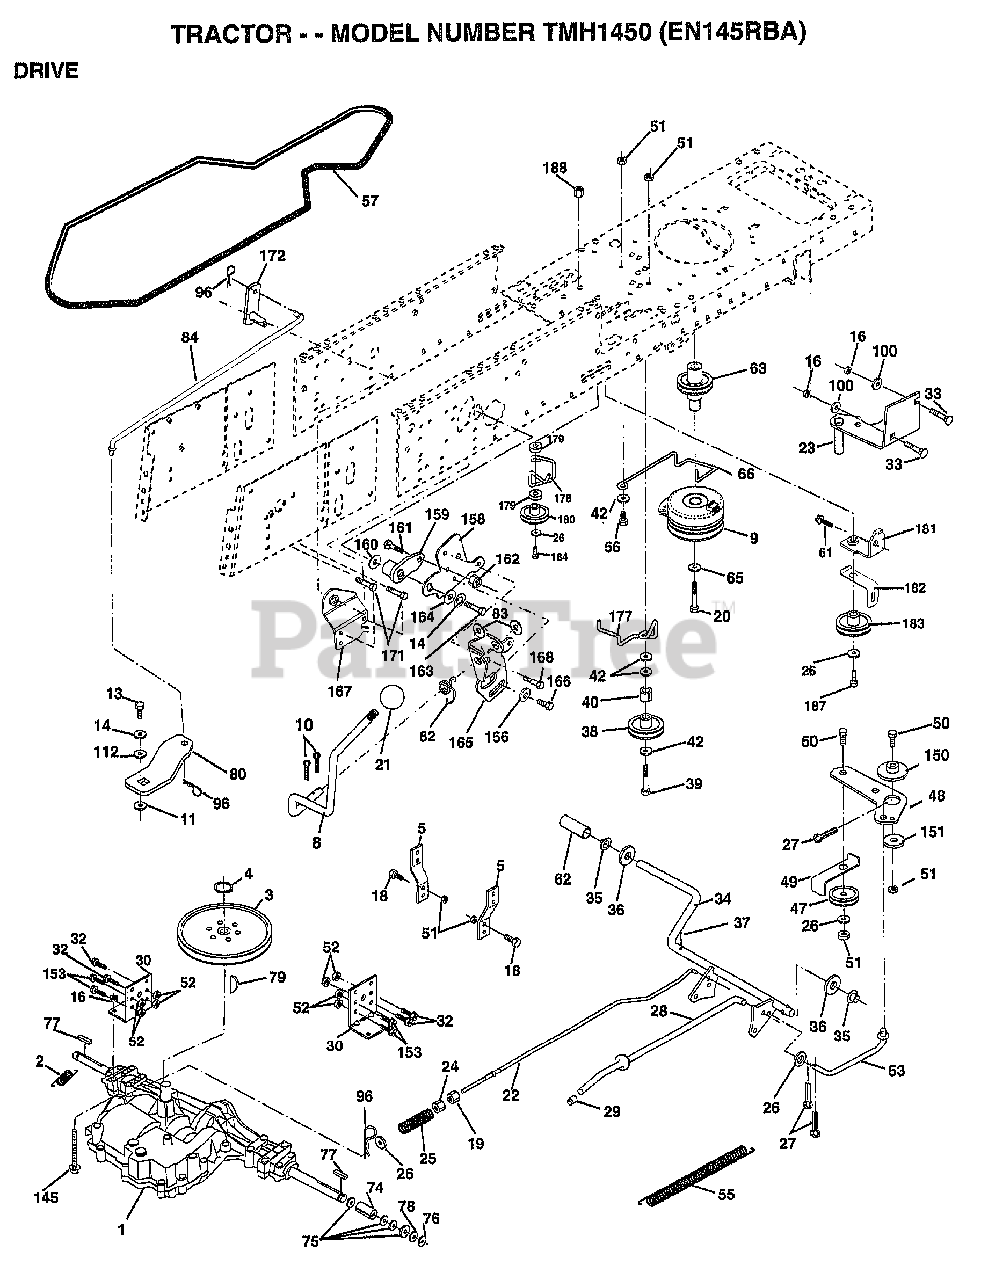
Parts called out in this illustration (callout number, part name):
2	SPRING.BRAKE.RETU
3	"PULLEY.TRANSAXLE.7"""
5	STRAP TORQUE
8	ROD.SHIFT.FENDER.ADJ.LT.CRD
9	CLUTCH.ELEC.EVX
10	PIN COTTER 1/8
11	WASH-SHFT PLT LT
13	BOLT.1/4-28.W/PAT
14	LOCKWASHER
16	NUT
18	BOLT
19	NUT
20	BOLT.7/16-20X4.25
21	KNOB T (1/2-HOLE)
22	ROD.BRAKE.PMST.CRD
23	BRACKET.CLUT.MTG.
24	NUT
25	SPRING ROD LT
26	WASHER
27	COTTER PIN
28	ROD.BRAKE.PARK.LT
29	PLUNGER CAP T
30	TRANSAXLE MTG BKT
32	BOLT
33	BOLT
34	SHAFT.ASM.PEDAL.FOOT.CRD
35	NYLON BEARING
36	WASHER LT
38	PULLEY.FLAT
39	BOLT
40	SPACER T
42	WASHER
48	BELLCRANK.CLUTCH
49	RETAIN BELT
53	"LINK, CLUTCH T"
55	"SPRING, RETURN LT"
57	"V-BELT.KEV.111"""
61	SCREW
62	PEDAL COVER T
63	PULLEY.CLUTCH.EVX
65	LOCKWASHER
66	KEEPER-BELT
74	SPACER AXLE
75	WASHER
76	E-RING LT
77	SQUARE KEY
78	WASHER
80	"ARM.SHIFT.20""TIRE"
82	"SPRING,TORSION"
83	WASHER
84	LINK.SHIFT.CRD
96	RETAINER M
100	WASHER M
112	WASHER LT
145	BOLT.HEX.FLGHD
150	BUSHING.BELLCRANK.GRD.DR
151	WASHER
156	WASHER.SRRTD.5/16
158	BRKT.SHIFT.MOUNT
159	HUB.SHIFT
160	WASHER
161	BOLT T
164	WASHER.5/8X.281X10GA
165	BRKT.PIVOT.LEVER
166	SCREW.5/16-18X5/8
167	BRKT.SUPT.SHIFT.CRD
168	BOLT.SHOULDER.5/16-18X.561
171	SCREW LT
172	SHAFT.ASM.SHIFT.FRT.CRD
177	KEEPOER.FLAT.IDLER
178	KEEPER.BELT.IDLER
179	WASHER
180	PULLEY.FLAT.IDLER
181	BRKT.IDLER.GRD.DR.CRD
182	"KEEPER.BELT.2.5"".OD.CRD"
183	PULLEY.V-IDLER
184	SCREW.HXWSH.3/8
187	SCREW
